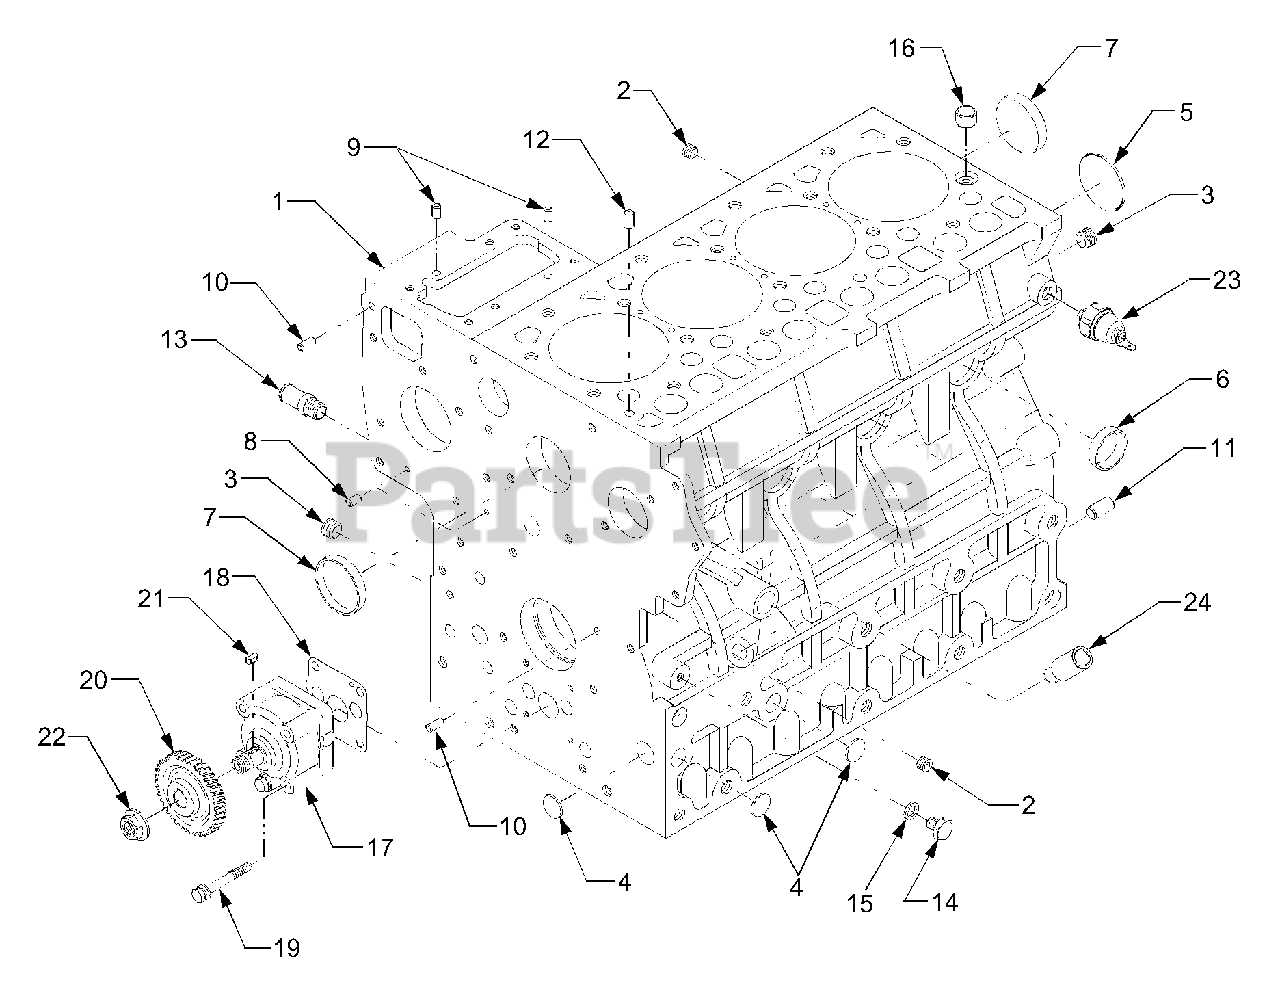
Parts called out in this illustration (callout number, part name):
1	Cylinder Block Ass'y
8	Pin, Straight
9	Pin, Straight
10	Pin, Straight
11	Pin, Straight
17	Oil Pump Ass'y
18	Gasket, Oil Pump
20	Gear, Oil Pump Drive
24	Guide, Oil Gauge
